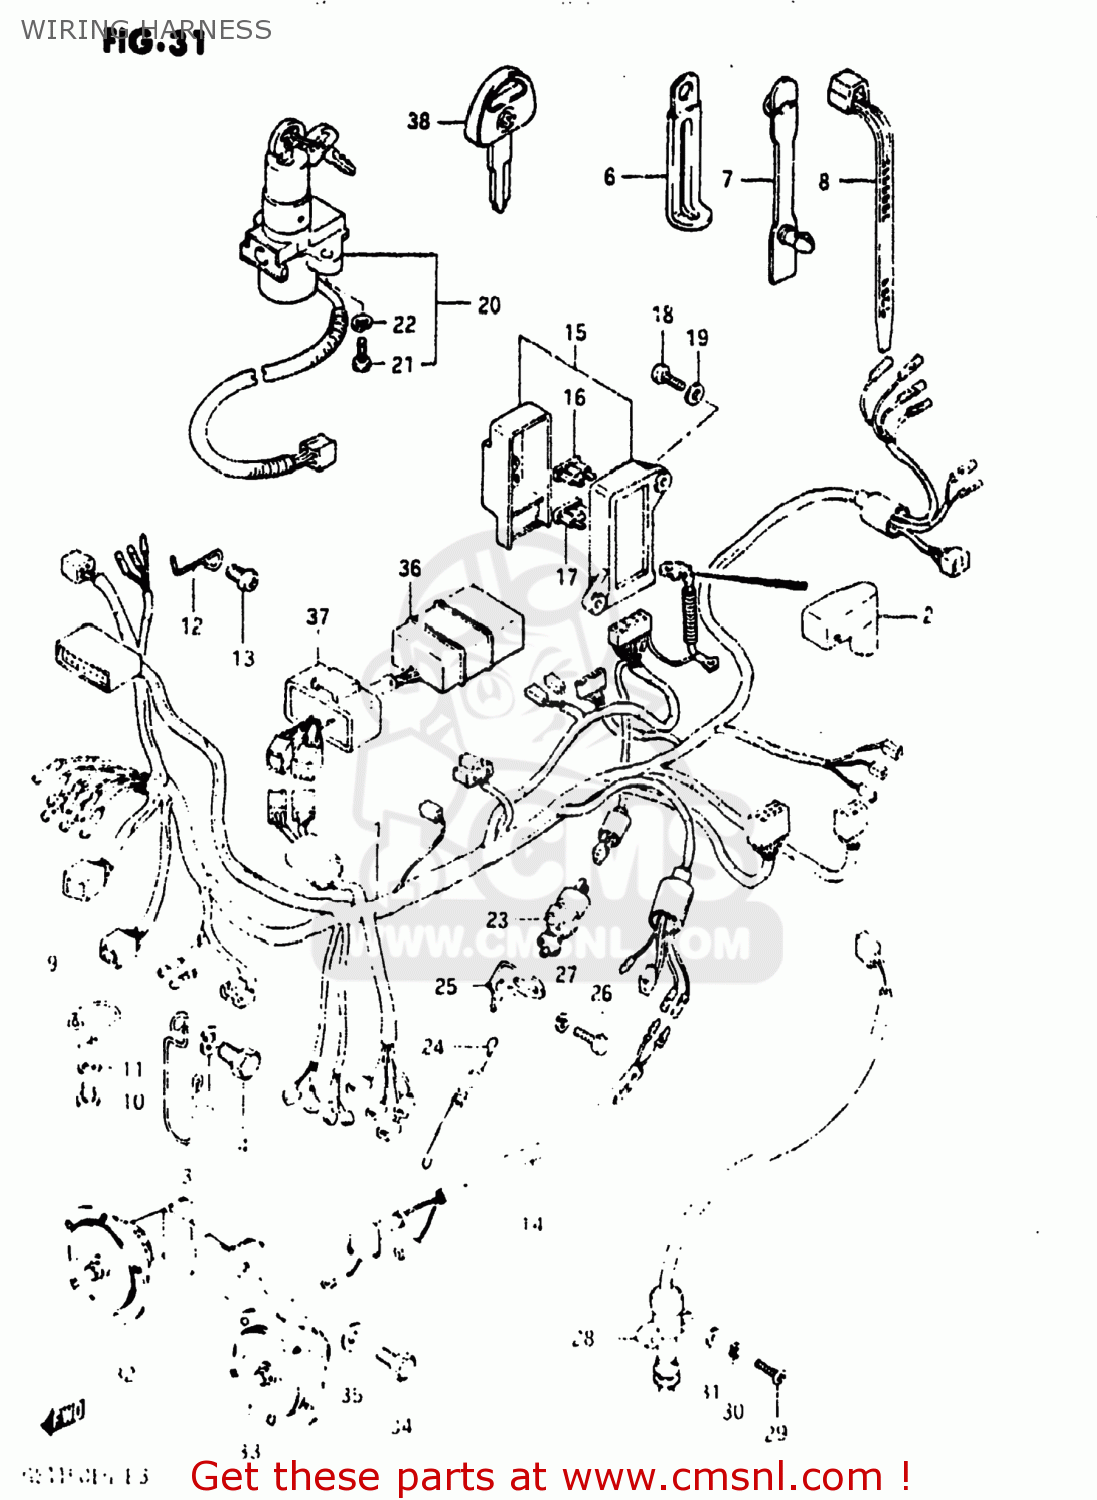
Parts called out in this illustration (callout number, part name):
1	HARNESS,WIRING
2	CAP,BATTERY PLUS
3	GUIDE,WIRING HARNESS
4	BOLT
5	WASHER,LOCK,8.
6	CLAMP
7	CLAMP,L:88
8	CLAMP(L:95)
9	CLIP,WIRING HARNESS
10	SCREW 6X12
11	WASHER
12	GUIDE,WIRING HARNESS
13	SCREW
14	WIRE,OIL TEMPERATURE GAUGE
15	BOX ASSEMBLY,FUSE
16	FUSE(10A)
17	FUSE(15A)
18	SCREW
19	WASHER
20	IGNITION SWITCH/STEERING LOCK
21	BOLT
22	WASHER,LOCK
23	SWITCH ASSEMBLY,STOP LAMP
24	SPRING
25	BRACKET,BRAKE LAMP SWITCH
26	BOLT
27	WASHER,LOCK
28	SWITCH ASSY,SIDE STAND WARNING
29	SCREW 5X20
30	WASHER,LOCK
31	WASHER,5MM
32	HORN ASSEMBLY,HIGH PITCH
33	HORN ASSEMBLY,LOW PITCH
34	BOLT
35	WASHER
36	RELAY,LAMP OUTAGE WARNING
37	STAY,LAMP OUTAGE WARNING
38	KEY,BLANK
